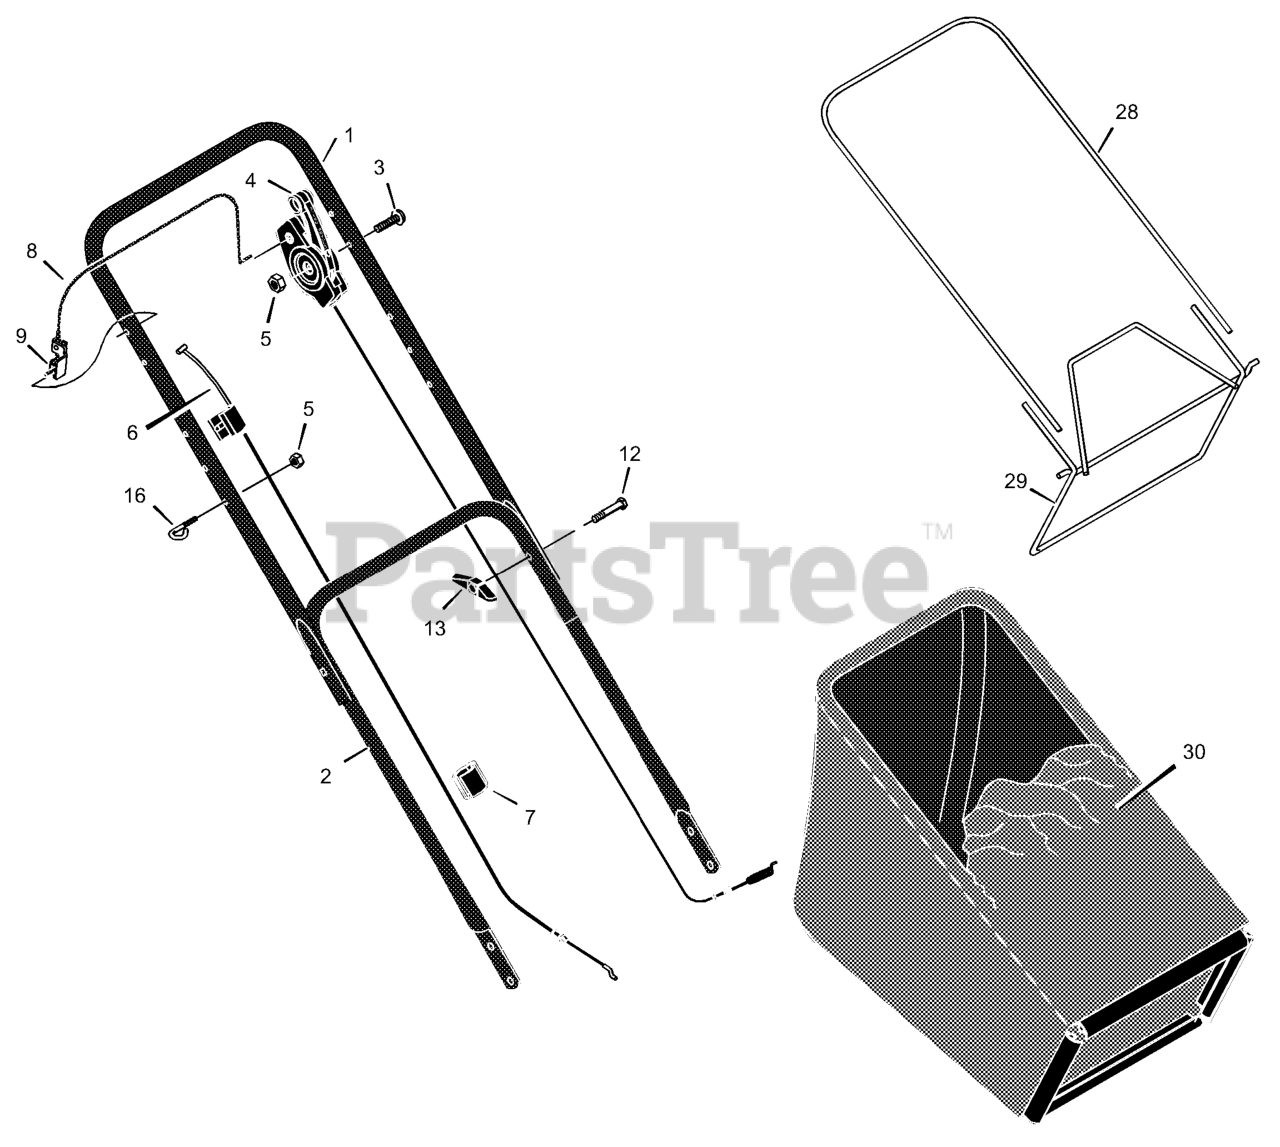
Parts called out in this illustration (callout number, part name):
1	Handle, Upper (Gray)
2	Handle, Lower (Gray)
4	Control, Drive
5	Locknut
6	Cable, Stop
7	Fastener, Cable
8	Engine Stop Lever
9	Bracket, Stop Lever
13	Knob
16	Guide, Rope
28	Frame, Top
29	Frame Assembly
30	Bag, Cloth
